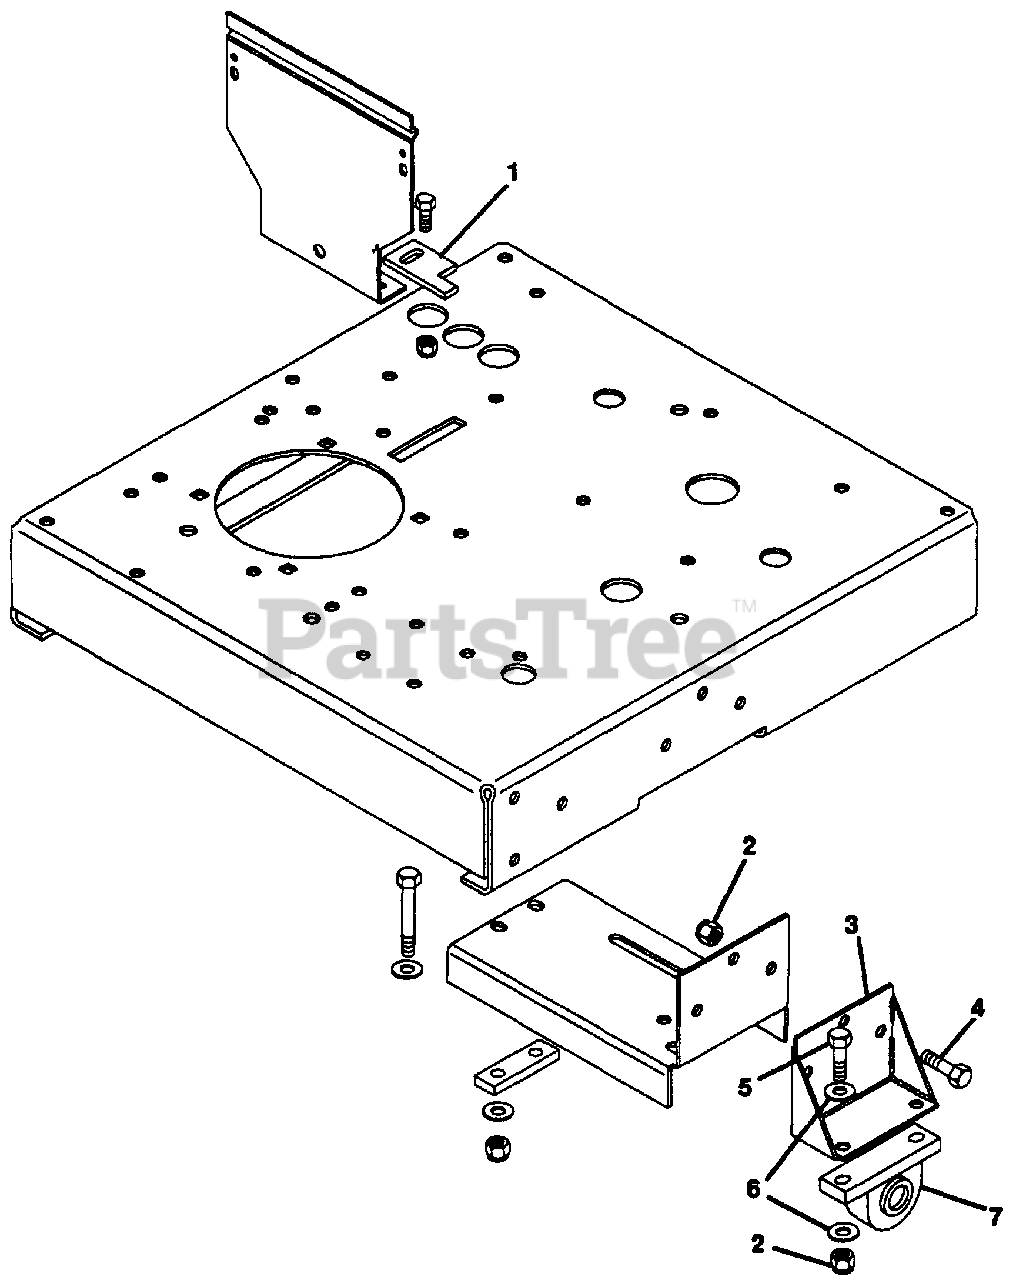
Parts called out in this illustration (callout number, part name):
1	Keeper
2	Nut, Lock 3/8-16
3	Weldment, Support
4	Bolt, Hex 3/8-16x1.25
5	Bolt, Hex 3/8-16x1.50
6	Washer, Flat .406x.812x.065
7	Bearing, Pillow Block
